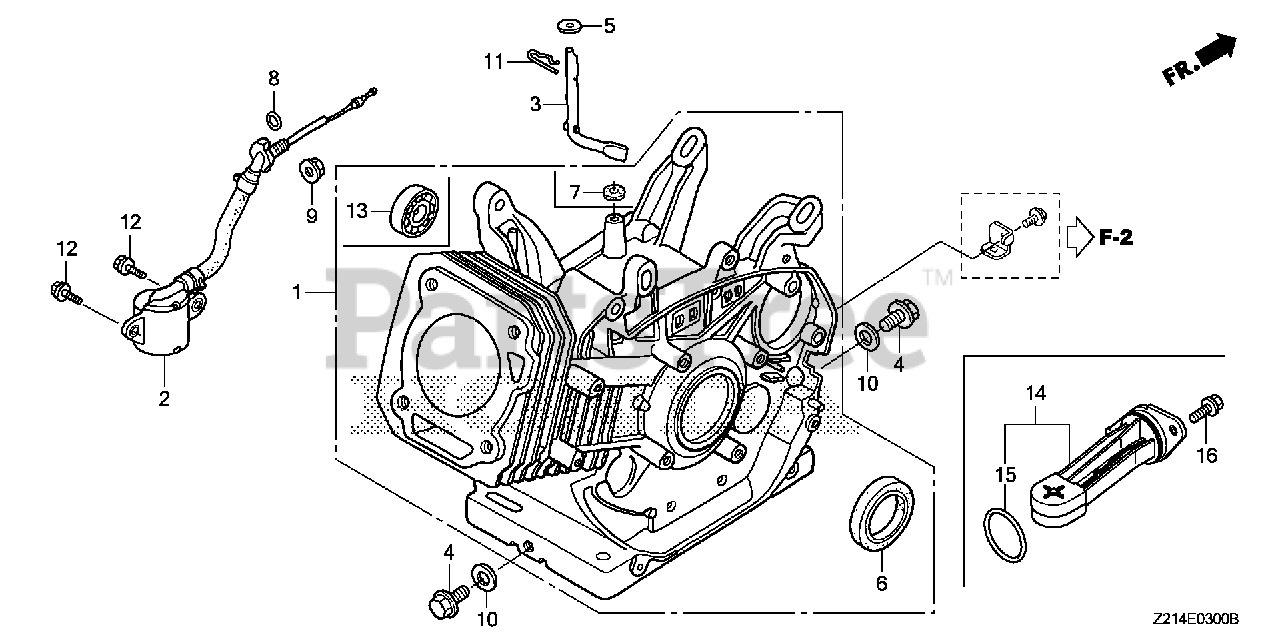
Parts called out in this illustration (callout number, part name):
1	CYLINDER ASSY. (SELF STARTER+ALERT)
2	SWITCH ASSY., OIL LEVEL
3	SHAFT, GOVERNOR ARM
4	BOLT, DRAIN PLUG
5	WASHER (8.2X17X0.8)
6	OIL SEAL (30X46X8)
8	O-RING (14MM) (ARAI) Use up to Engine SN 2949254.
9	NUT, FLANGE (10MM)
10	WASHER, DRAIN PLUG (12MM)
11	PIN, LOCK (10MM)
12	BOLT, FLANGE (6X12) Use up to Engine SN 1543277.
